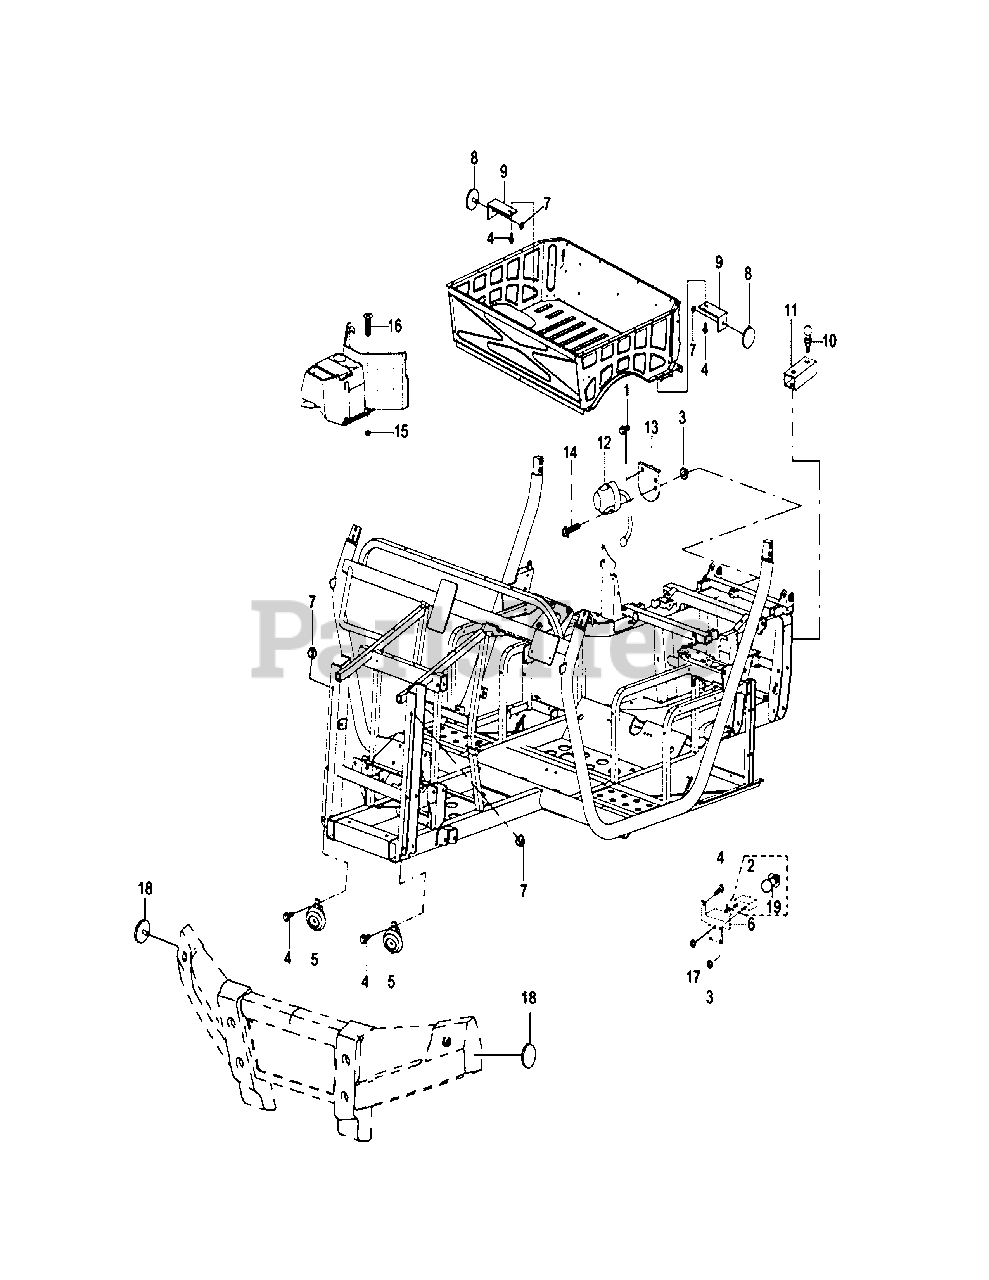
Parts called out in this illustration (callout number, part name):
1	Hexagon Flange Bolt M6×16
2	Rear License Light
3	Hexagon flange nut M5
4	Hexagon Flange Bolt M6×12
5	Horn Assy
6	License Plate Support
7	Hexagon Flange Nut M6
9	Reflector Mounting Plate
10	Hitch Bar
11	Connector I (T001)
11	Connector II (T002)
11	Connector III(T003)
11	Connector VIII (T008)
12	Socket Outlet for Trailer
13	Mounting Board for Socket Outlet
14	Screw M5×30
15	Sundry Box
16	Cross Large Plate Head Screw M6×30
17	I-Shaped Rubber Ring IV
19	Position Light Bulb (12V 5W)
